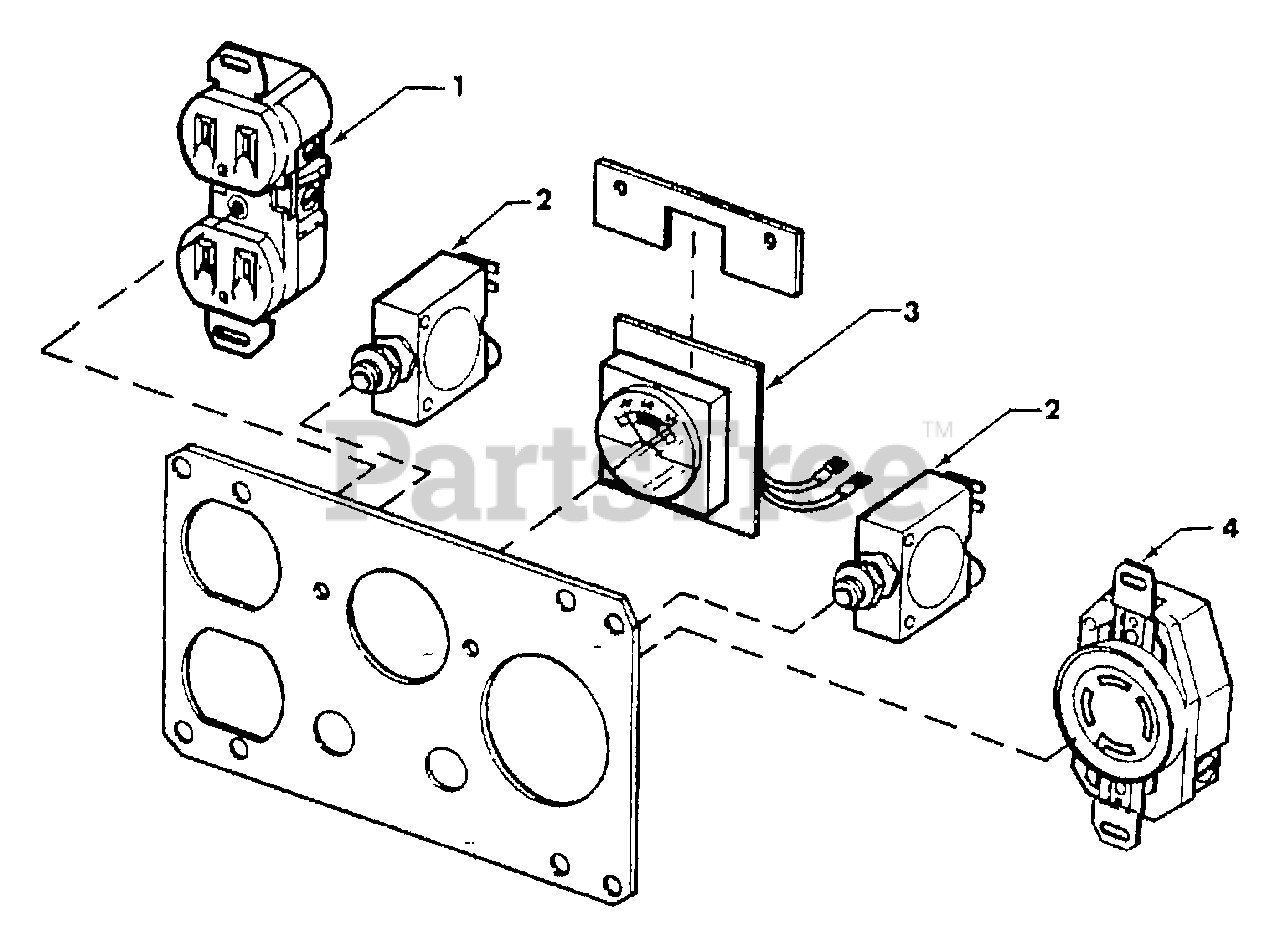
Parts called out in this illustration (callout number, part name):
1	RECEPTACLE-120 VOLTS
2	BREAKER-CIRCUIT
4	RECEPTACLE
